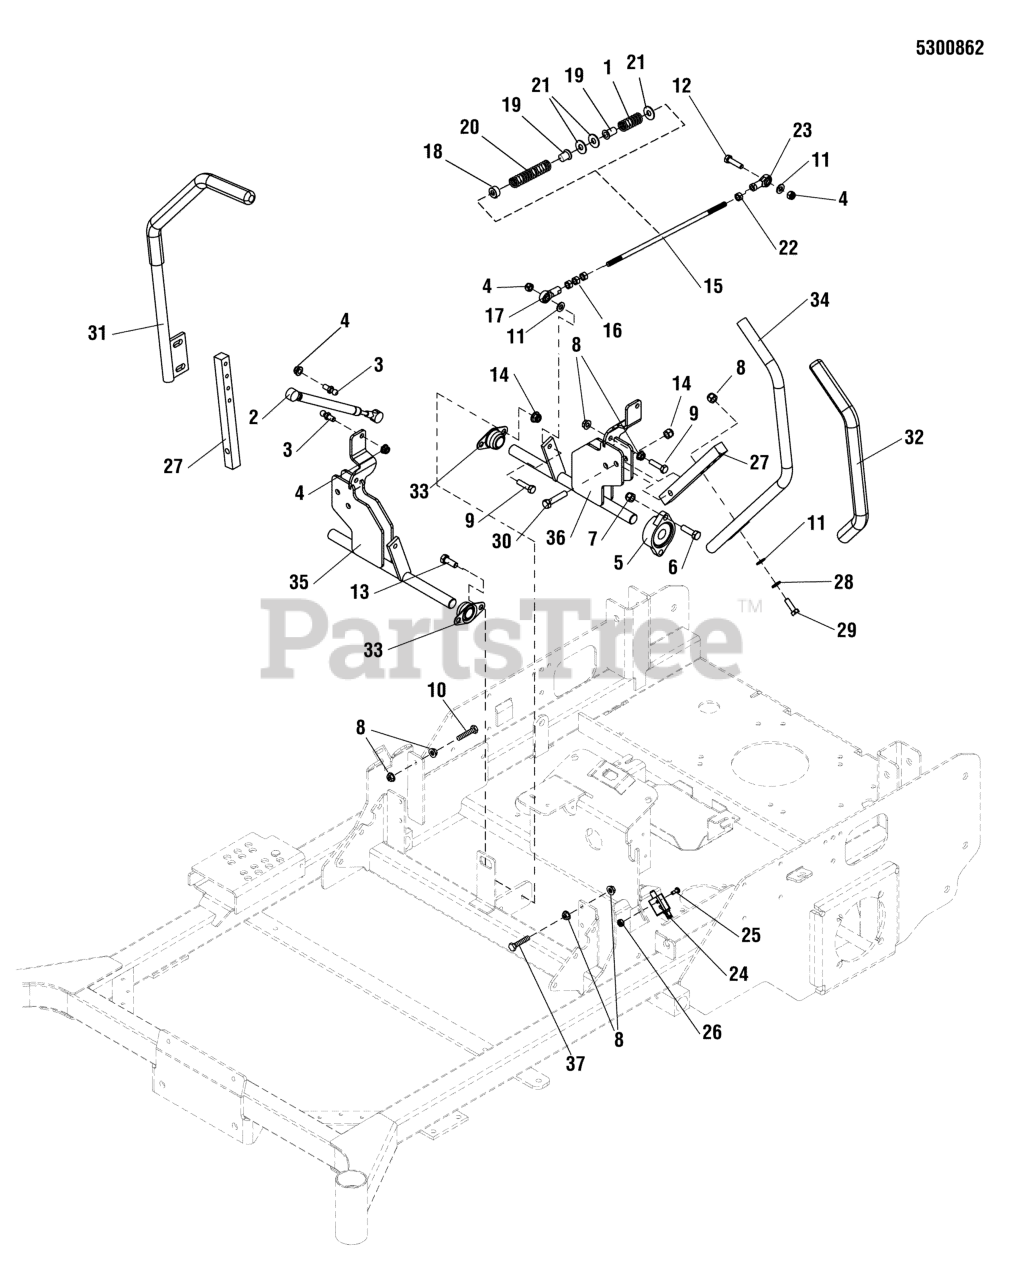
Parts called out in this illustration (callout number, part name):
1	SPRING-COMP, .594 ID X 1.75 LG X .080 WR
2	DAMPENER, CONTROL,#(P6709/P3610)
3	BALL STUD, 5/16 X .50,# PC-477-2)
4	NUT, 5/16-18 HEX NYLOCK FLANGE
5	BEARING, FLANGE
6	BOLT, 3/8-16 X 1-1/4 SHCS
7	NUT, 3/8-16 HEX NYLON LOCK
8	NUT, 5/16-18 HEX SERRATED FLANGE (SMALL)
9	BOLT, 5/16-18 X 1-1/4 GD5 YZ
10	BOLT, 5/16-18 X 1-3/4" GD5 TFL
11	WASHER, 5/16" SAE
12	BOLT, 5/16-18 X 1-1/8 GD5
13	BOLT, 3/8-16 X 1" GD5 CZ
14	NUT, 3/8-16 HEX NYLOCK FLANGE
15	ROD, HYDRO CONTROL
16	NUT, 5/16-24 HEX
17	BALL JOINT 5/16-24 RH FEMALE STAMPED STL
18	COLLAR, 5/16" SET
19	BUSHING, NYLON
20	SPRING, REVERSE RETURN
21	WASHER, 5/16" FENDER
22	NUT, 5/16-24 HEX, LH
23	BALL JOINT 5/16-24 LH FEMALE STAMPED STL
24	SWITCH, PLUNGER, N.O.
25	SCREW, #10-24 X 1/2 ROUND PHILLIPS
26	NUT, #10-24 HEX
27	MOUNT, CONTROL ARM - BLK
28	WASHER, 5/16 LOCK CZ
29	BOLT, 5/16-18 X 1 GD5 YZ
30	BOLT, 3/8-16 X 1-3/4" GD5 CZ
31	WELD, HANDLE MOTION CONTROL, RH - BLK
32	GRIP, FOAM, 3/4 ID, 16 LONG
33	BEARING, BRONZE FLANGE, 3/4
34	WELD, HANDLE MOTION CONTROL, LH - BLK
35	WELD, CONTROL SHAFT, RH - RED
36	WELD, CONTROL SHAFT, LH - RED
37	BOLT, 5/16-18 X 1-1/4 GD5 TFL, CZ
